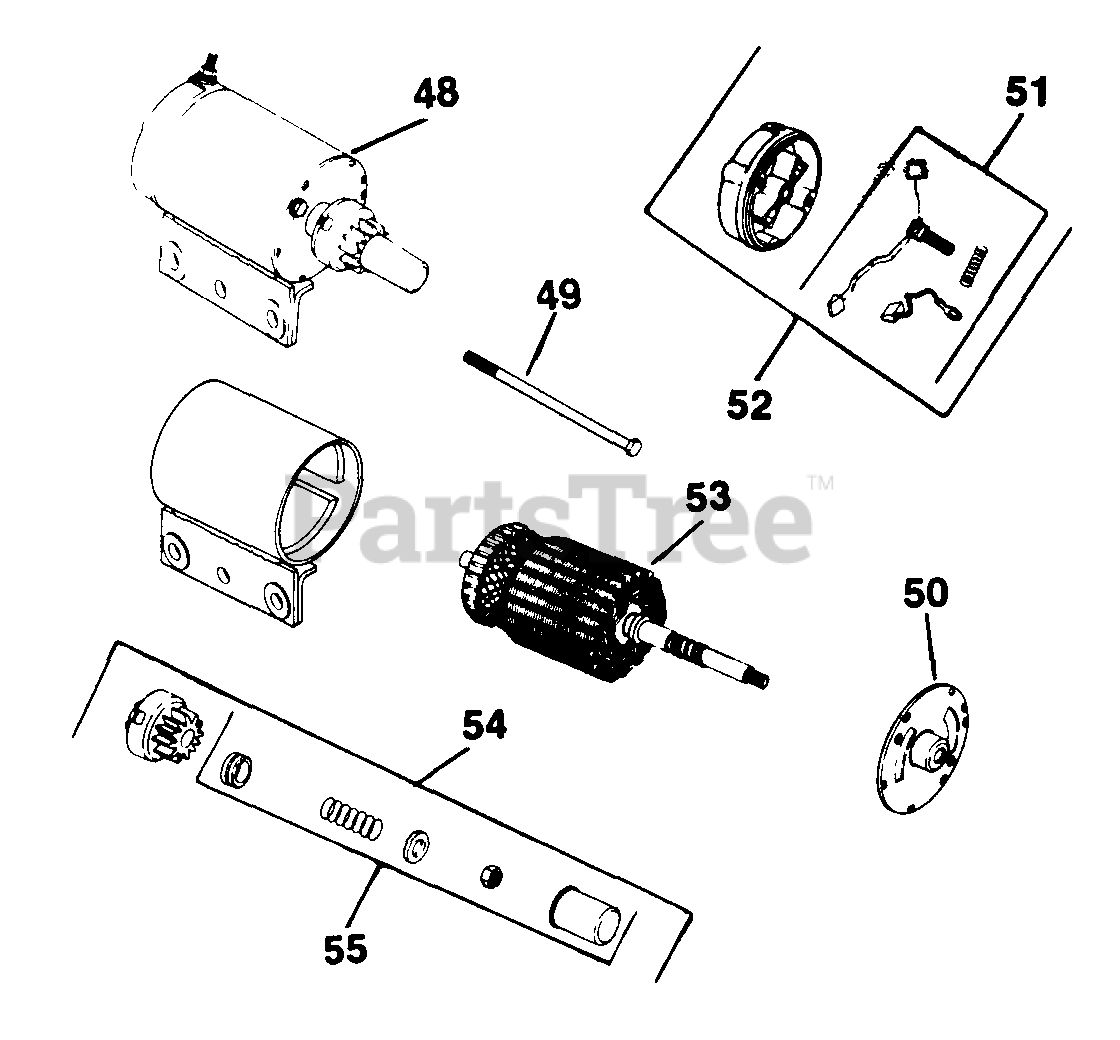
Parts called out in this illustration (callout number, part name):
48	STARTER - USE 45 098 09
50	CAP - USE 45 081 05
51	KIT - USE 82 755 28
52	CAP - DISCONTINUED
53	ARMATURE - DISCONTINUED
X-22-1-S	WASHER, SPRING LOCK 3/8"
